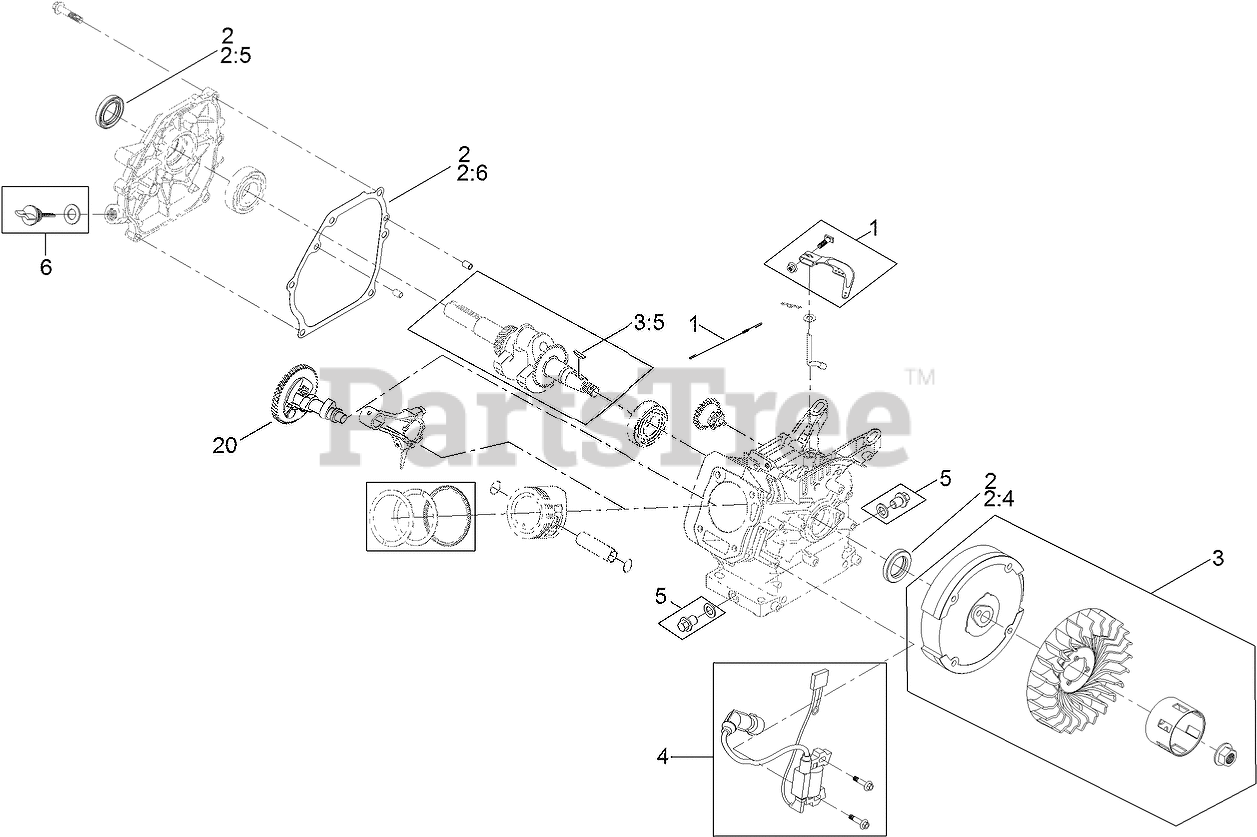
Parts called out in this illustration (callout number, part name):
1	GOVERNOR KIT
2	GASKET AND SEAL KIT
2:5	SEAL-OIL
2:6	GASKET-COVER, CRANKCASE
3	RECOIL FLYWHEEL KIT
3:5	KEY-WOODRUFF
4	IGNITION KIT
5	DRAIN PLUG KIT
6	DIPSTICK AND O-RING KIT
20	CAMSHAFT
